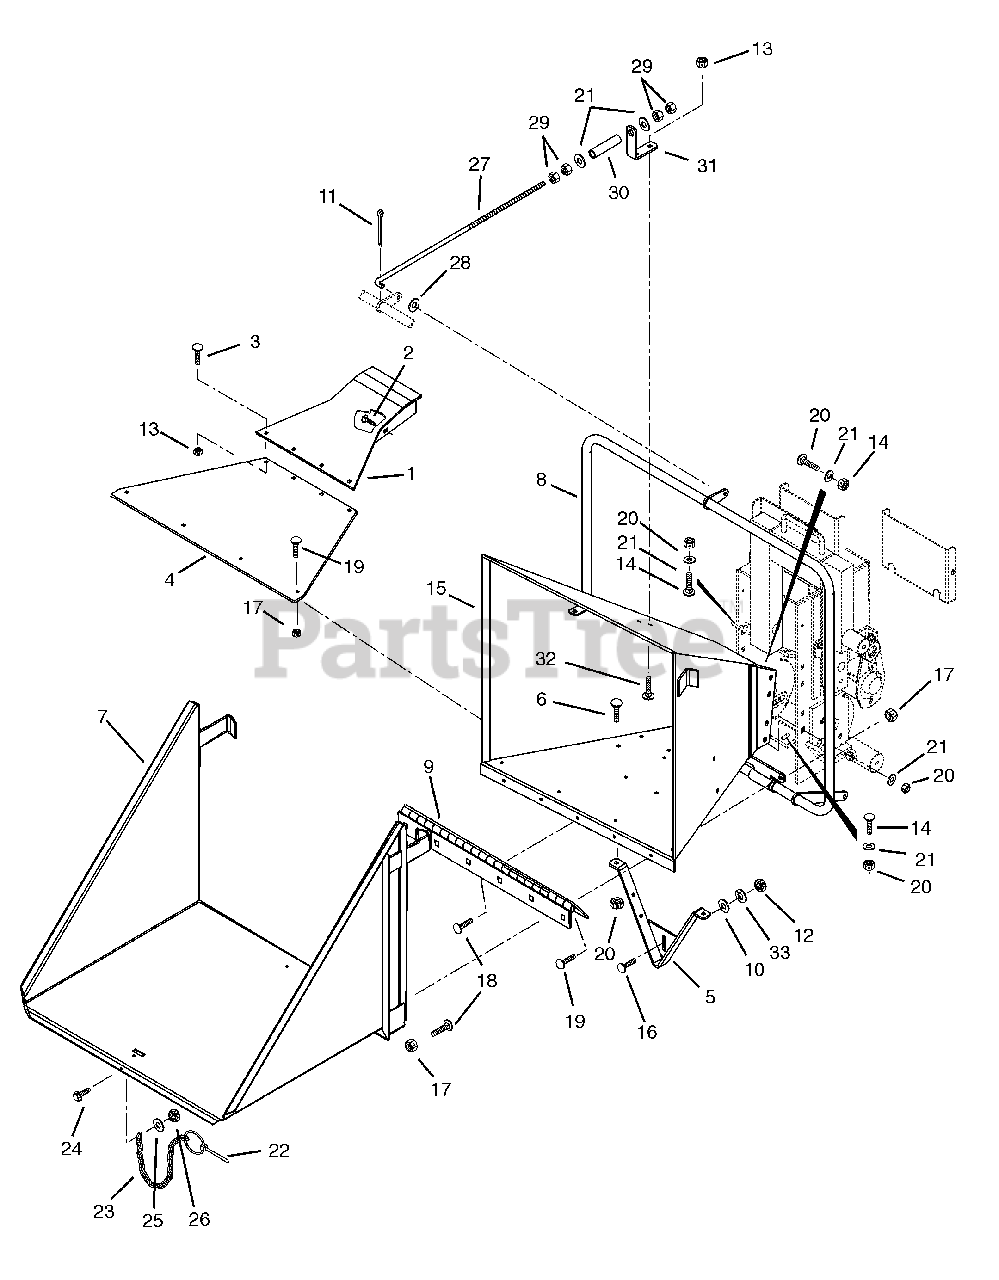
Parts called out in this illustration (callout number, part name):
1	Replacement-Bottom Feed Roll
2	Bolt-Round Head Square Neck .38 X 1.25 Grade 2
3	Bolt-Round Head Square Neck .31-18 X 1.25 Grade 2
4	Plate-Skid-Bottom Feed Roll
5	Pedestal-Hopper Weldment Assembly
6	Bolt-Round Head Square Neck .31-16 X 1.25
7	Apron Weldment
8	Bar-Feed Control Weldment Assembly
10	Washer-Flat-Steel .563 X 1.38 X .109
11	Pin-Cotter .12 X .75
12	Nut-Hex .50-13
13	Nut-Lock-Center .31-18
14	Bolt-Round Head Square Neck .38-16 x 1.00
15	Hopper Weldment
16	Bolt-Round Head Square Neck .50-13 X 1.25 Grade 2
17	Nut-Locking-Center .25-20
18	Bolt-Round Head Square Neck .25-20 X .50 Grade 5
19	Bolt-Round Head Square Neck .25-20 X .75 Grade 2
20	Nut-Locking-Center .38-16
21	Washer-Flat-Steel .438 X 1.00 X .083
22	Pin-Lock .31 X 2.00
23	Chain-5 Straight Link #4
24	Screw-Machine 10-24 w/Insert
25	Washer-Flat-Steel .219 X .50 X .049
26	Nut-Locking-Nylon 10-24 w/Insert
27	Rod-Valve Stop
28	Washer-Flat-Steel .344 X .688 X .065
29	Nut-Hex .38-16
30	Tubing Urethane .438 X .688
31	Bracket-Valve Stop
32	Bolt-Round Head Square Neck .31-18 X .75 Grade 5
33	Washer-Locking .50 x 1.25
